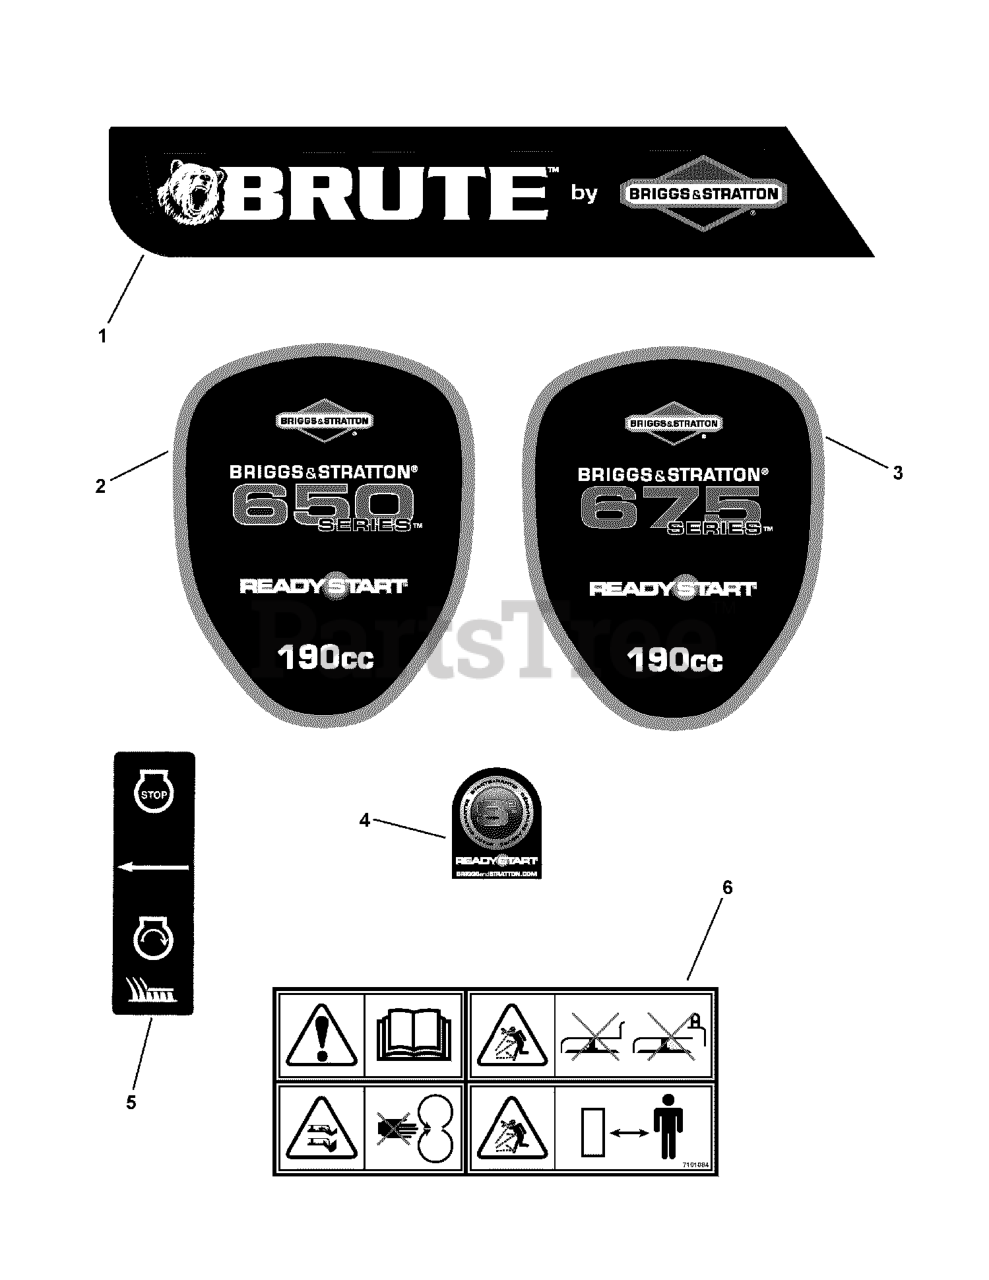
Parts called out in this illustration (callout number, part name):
1	DECAL, Deck Front 22"
2	DECAL, 650 Series Ready Start
3	DECAL, 675 Series Ready Start
4	DECAL, Readystart
5	DECAL, OPC Bail International Symbol
6	DECAL, Warning, Euro, Multi-Panel
